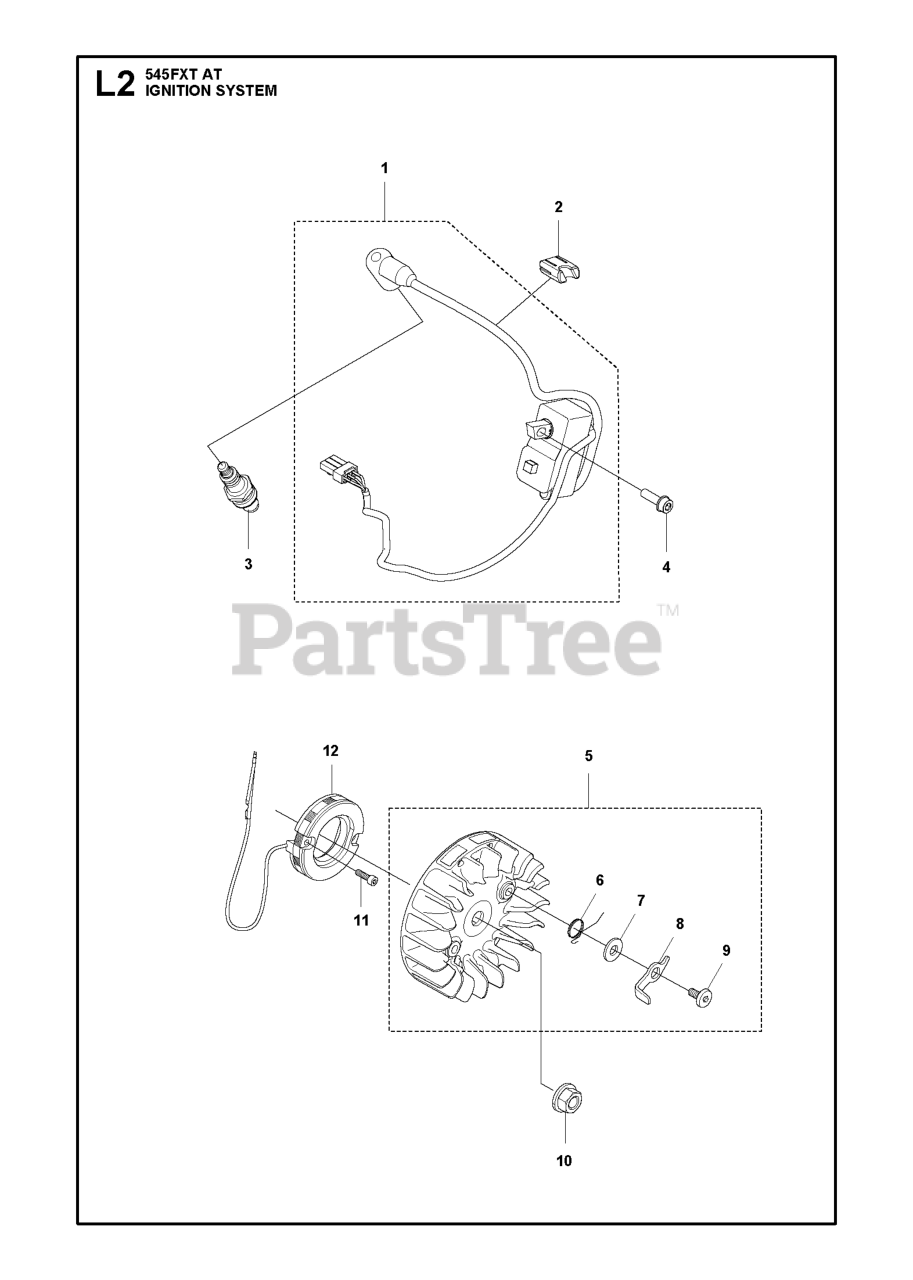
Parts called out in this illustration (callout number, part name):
1	FLANGE BEARING
2	BRAKE CROSS SHAFT
3	BRAKE LEVER WLDMT
4	GRIP, PARK BRAKE
6	CALIPER ASSEMBLY
8	PLATE, BRAKE
9	SB 3/8-16 X 2-1-1/2 SKT HDD ZD
10	LINKAGE, BRAKE
11	NUT 3/8-24 JAM
12	BRACKET, L
14	LINKAGE, REAR BRAKE
15	MACHINE BUSHING
16	NUT 3/8F CENTERLOCK
17	NUT HEX 3/8-16 NYLON, THIN
18	COTTER PIN 3/32 X 3/4
19	WASHER 3/8 SAE FLAT
20	HCS 3/8-16X1.GRD.5.ZD
21	WHEEL/TIRE.ASM.23X9.5-12.GREY
22	TIRE.TURF.MASTER.23X10.5-12
23	RIM 0 OFFSET 8.5" WIDE
24	VALVE STEM TR-412
25	RETAINING RING, 7/8"
26	NUT 1/2-13 HEX NYLOC ZD
28	LUG NUT 1/2F
29	HCS 1/2C X 2 3/4
30	PIN COTTER 4MM X 45MM
31	MOTOR STANDOFF
32	TL15 WHEEL MOTOR
33	WASHER 1/2" SPLIT LOCK
34	NUT HEX 1/2
35	NUT 3/4-16 HEX SLTD GR5 ZD
36	BSHG .875 X 1.375 X .074 ZD
37	NUT.1/4-20.HEX.NYLOC.ZD
38	NUT 3/8-16 NYLOC
39	HCS 1/4C X 3/4 HCS
40	NUT 3/8C WHIZ
41	HCS 1/2C X 1 1/4 SERRATED HEAD
42	HCS 3/8C X 2 1/2
